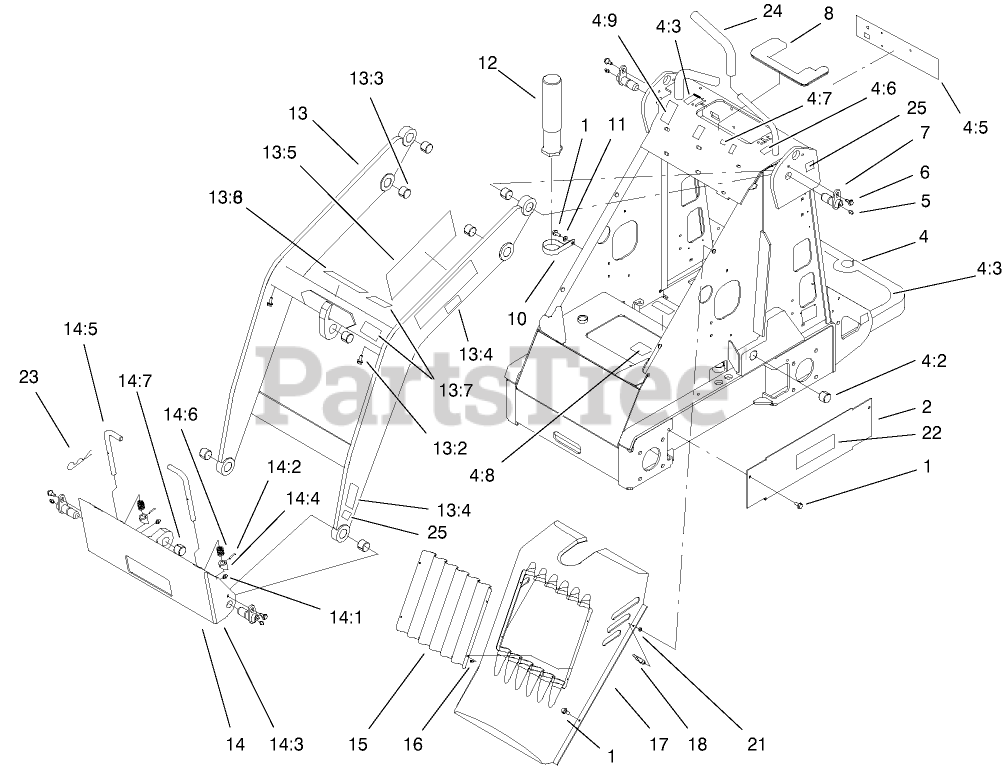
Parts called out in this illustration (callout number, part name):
1	SCREW-HWHTF
2	COVER-HOSE
4	Frame & Decal ASM
4:2	BUSHING-TENSION
4:3	TREAD-FOOT
4:5	DECAL-PANEL, CONTROL
4:6	DECAL-THROTTLE
4:7	DECAL-LIMITER, SPEED
4:8	DECAL-OIL, HYD
4:9	DECAL-SELECTOR
5	FITTING-GREASE
6	BOLT-SHOULDER
7	PIN-PIVOT
8	COVER-VALVE
10	CLAMP-R
11	WASHER-PLAIN
12	TUBE-MANUAL
13	LOADER ASM
13:2	SCREW-HWHTF
13:3	BUSHING-TENSION
13:4	DECAL-WARNING
13:5	DECAL-DANGER
13:6	DECAL-CAUTION
13:7	DECAL-NO RIDERS
14	QUICK ATTACH ASM
14:1	FITTING-GREASE
14:2	PIN-SPECIAL
14:3	MOUNT-ATTACH, QUICK
14:4	CAM-ATTACH, QUICK
14:6	SPRING-COMPRESSION
14:7	BUSHING-TENSION
15	GRILLE-SCREEN
16	SCREW-PPH
17	Cover-Hood
18	LATCH-SWELL
21	WASHER
22	DECAL-4-PAW
23	PIN-COTTER
24	GRIP-CUSHION
25	DECAL-POINT, LIFT
